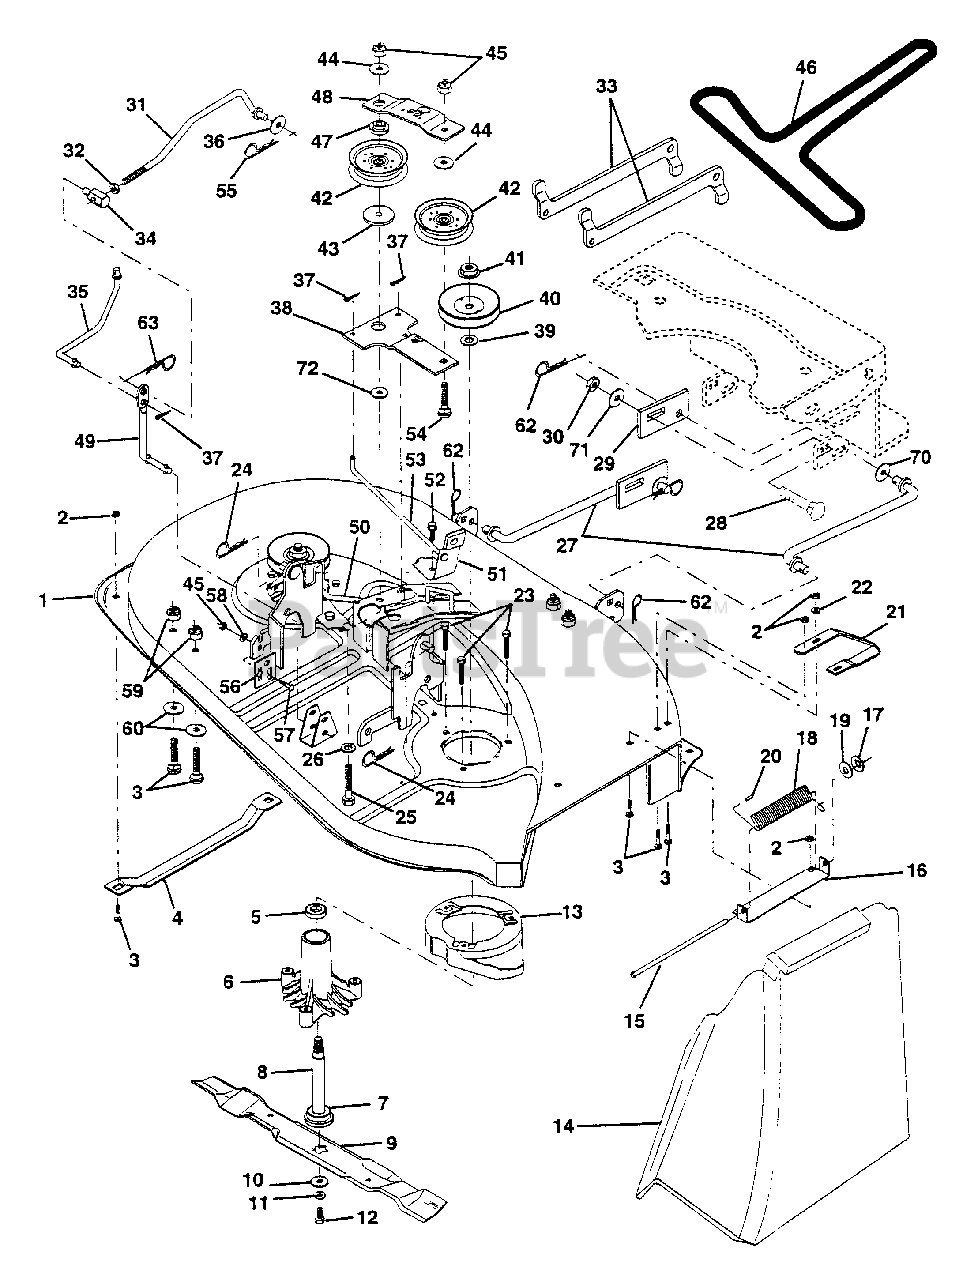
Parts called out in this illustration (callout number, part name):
1	Mower Deck Assembly
2	Nut, Lock Hx w/Ins 5/16-18
3	Bolt, Carriage 5/16-18 x 3/4
4	Runner, L.H.
6	Housing, Mandrel
8	Shaft and Bearing Assembly, Mandrel
10	Washer, Hardened
11	Washer, Lock 3/8
12	Bolt, Hex 3/8-24 x 1-1/4 Grade 8
13	Stripper, Mower, Vented
14	Shield, Deflector
15	Rod, Hinge
16	Bracket Assembly, Deflector
18	Spring, Deflector
19	Washer 11/32 x 5/8 x 16 Gauge
20	Cap, Sleeve
21	Runner, R.H.
22	Washer 11/32 x 3/4 x 16 Gauge
23	Screw Thdrol Hex Head Zinc MWR
24	Retainer, Spring
25	Bolt Hex 3/8-16 x 2-1 /4
26	Washer 13/32 x 1 x 12 Gauge
27	Link Assembly, Front
28	Bolt RDHD SQNK 3/8 - 16 x 1
29	Plate Slide Link
30	Nut, Lock Hex w/washer 3/8 - 16
31	Clutch Rod, Primary
32	Nut, Hex, Jam 3/8-16
33	Arm, Suspension, Rear
34	Trunnion 3/8-16
35	Clutch Rod, Secondary
36	Washer 13/32 x 13/16 x 16 Gauge
37	Pin, Cotter 3/32 x 3/4
39	Washer .150 Thick
40	Pulley, Mandrel
41	Nut, Flangelock 9/16
42	Pulley, Flat Idler
43	Spacer, Retainer
44	Washer 13/32 x 1 x 12 Gauge
45	Nut, Lock Hex W/Ins. 3/8-16 UNC
46	Belt
47	Spacer, Idler Arm
48	Stiffener, Idler Arm
49	Rod, Pivot
50	Rod, Brake, L.H.
51	Brake Assembly
52	Screw, Hex Washer Head, Thd., Roll. 5/16-18 x 3/4
53	Rod, Brake, R.H.
54	Bolt, Carriage 3/8-16 x 1-3/4 Grade 5
55	Spring, Retainer
56	Adjustment Plate, Rear Link, L.H.
57	Bolt, Carriage 3/8-16 x 1
58	Washer 13/32 x 3/4 x 12 Gauge
59	Locknut, Hex, with Washer Insert 5/16-18
60	Washer 11/32 x 11/16 x 12 Gauge
62	Retainer Spring
63	Retainer Spring
70	Washer 1/2 x 1-1/4 x 16 Ga.
71	Washer Flat 13/32 x 1 x 10 Ga.
72	Washer Hardened
